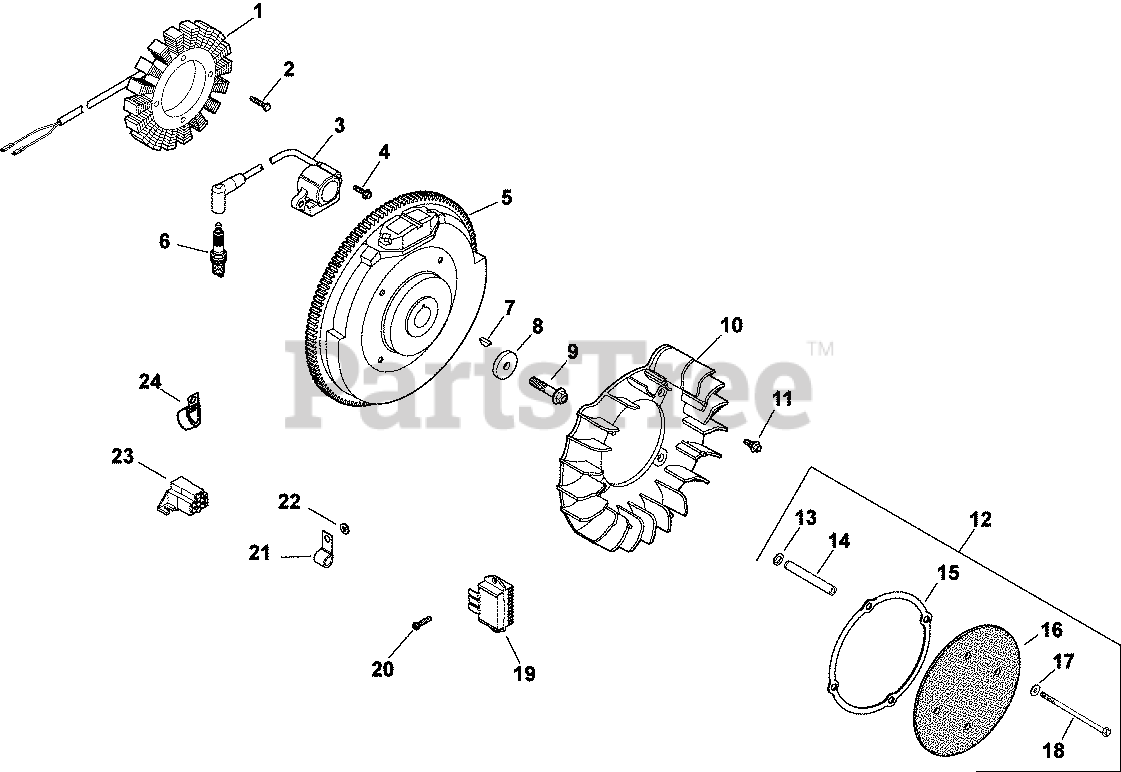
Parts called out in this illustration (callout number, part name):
1	KIT, 15 / 20 AMP STATOR
2	SCREW, M5X0.8X25 - (#25086402S)
3	KIT, MODULE IGNTN (CDI FIXED)
4	SCREW, FLG THD FRM M5X.8X20-(#25086399S)
6	PLUG, SPARK (STD)
7	KEY, 3/16" X 5/8"
8	WASHER, FLAT 13/32"
9	SCREW, FLG M10X1.5X45 - (#25086361S)
10	FAN - USE (#24 157 11-S)
11	SCREW, SKT SET #10-24X1/4"
12	KIT, CHOPPER SCREEN
13	WASHER, SPRING 10 MM
15	RING, SUPPORT USE 25 141 08-S
16	SCREEN, GRASS
17	WASHER, FLAT 1/4" (O.D. 5/8")
18	SCREW, CAP M6X1.0X99.5
19	REG/RECT-15 AMP (KM)-USE 41 403 10-S
20	SCREW, HEX FLANGE HI-LO
21	CLIP, CABLE
22	WASHER, FLAT 1/4" (O.D. 1/2")
23	CONNECTOR
24	CLIP, TUBE & WIRING (KM)
